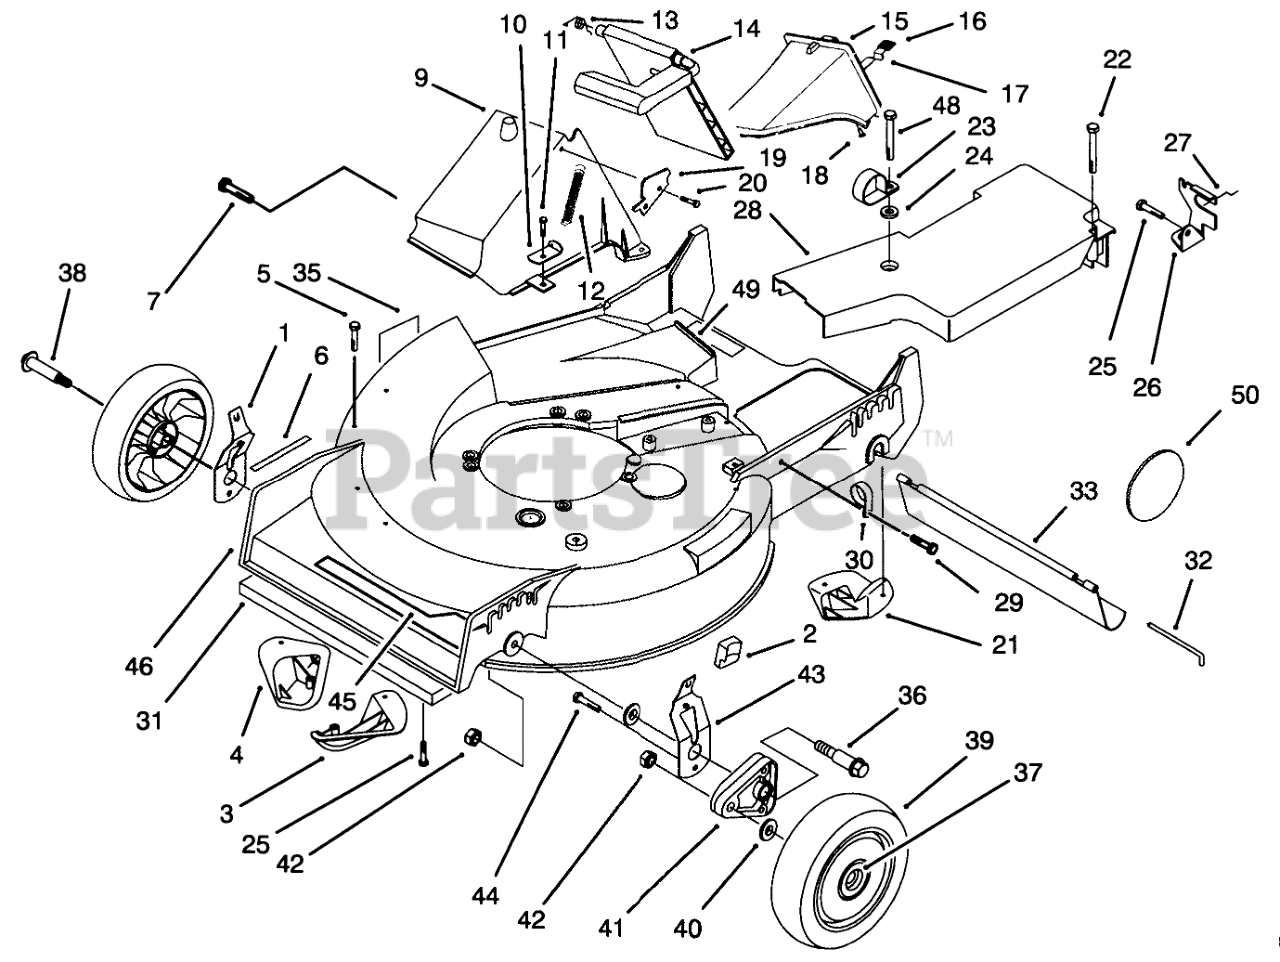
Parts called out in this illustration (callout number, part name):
1	RH SPRING ARM ASSEMBLY
2	KNOB-ARM
3	KICKER-FRONT
4	KICKER-RH
5	SCREW-PPH
6	DECAL - HOC
7	SCREW AND WASHER ASM
9	TUNNEL-DISCHARGE
10	BRACKET-SPRING
11	SCREW-HWH
12	SPRING-DOOR
13	RETAINER-DOOR
14	DOOR ASSEMBLY
15	Discharge Plug Assembly (Incl. Ref. #16-18)
16	GRIP-LATCH
17	LATCH-PLUG, DISCHARGE
18	RIVET-HEAD, FLAT
19	DOOR LATCH PLATE
20	SCREW-PLASTITE
21	KICKER-REAR
22	SCREW-HHFTF
23	CLAMP-CABLE
24	WASHER
25	SCREW-HWHTF
26	Bracket-Adj. Trac
27	RETAINER-CABLE
28	BELT COVER
29	SCREW-HWH
30	CLAMP-CABLE
31	Shield-front
32	ROD-SHIELD
33	SHIELD-TRAILING
35	DECAL - DIN/DANGER
36	BOLT-SHOULDER
37	BUSHING
38	BOLT-WHEEL
39	Wheel & Tire Assembly (Incl Ref. #37)
40	WASHER
41	ARM-PIVOT, FRONT
42	NUT-LOCK
43	LH SPRING ARM ASSEMBLY
44	SCREW-HWH
45	DECAL - DECK
46	Housing Assembly (Incl. Ref. #3-6,& 21 pg.1) (Incl. Ref. #5 & 6 pg.3)
48	SCREW-SPECIAL
49	DECAL FRENCH REGUL.
50	COVER-WHEEL
